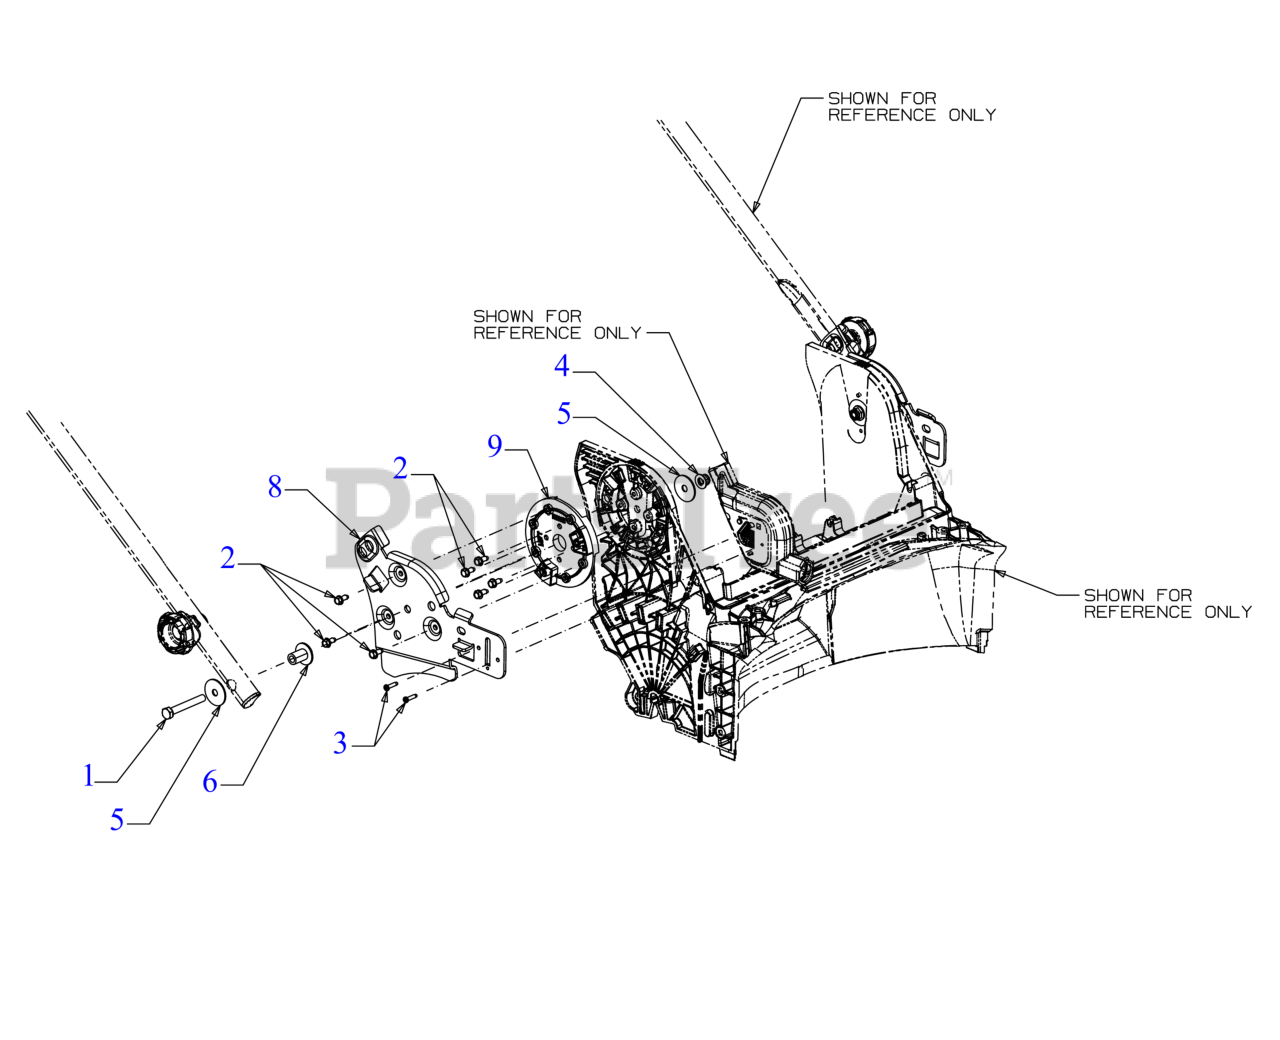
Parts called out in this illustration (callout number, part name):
1	HEX SCREW 5/16-18 x 2.25 GR5
2	HEX SCREW #12-16 x .50
3	SCREW-TAP PLASTIC #6-19 X 0.62
4	FLANGE LOCK NUT 5/16-18
5	FLAT WASHER 0.315x1.255x0.060 HD
6	SHOULDER SPACER 0.3146x1.0236x0.0708
8	HANDLE BRACKET (RH)
9	HANDLE MOUNT COUPLING
